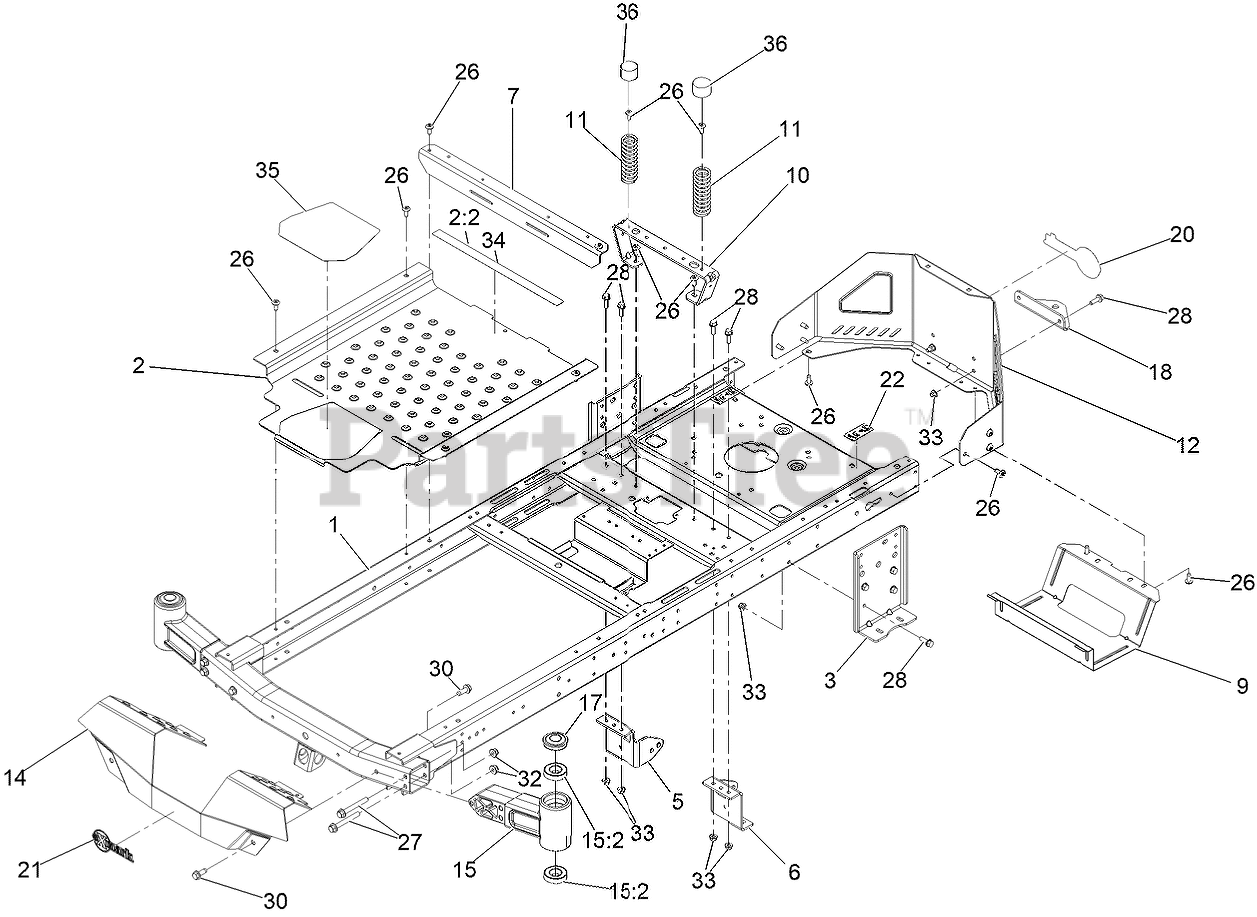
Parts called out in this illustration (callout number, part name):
1	FRAME ASM - RIVETED/WELDED
2	Pan-Floor ASM
2:2	DECAL-WARNING
3	PLATE-MOUNT, HYDRO
5	MOUNT-HYDRO, FRONT (RIGHT
6	Mount-Hydro, Front (Left)
7	BRACE-CROSS
9	GUARD-MUFFLER
10	SUPPORT-SEAT
11	SPRING-COMPRESSION
12	GUARD-ENGINE
15	AXLE-STUB
15:2	BEARING-BALL
17	Cap-Grease
18	BRACKET-HITCH
20	DECAL-EXMARK LOGO
21	DECAL-EXMARK LOGO
22	DECAL-BYPASS
27	SCREW-HHF
28	SCREW-HHF
30	SCREW-HWH
32	NUT-HF, NI
33	NUT-HF, NI
34	DECAL-WARNING
35	TREAD-STEP
36	CAP-PROTECTOR
